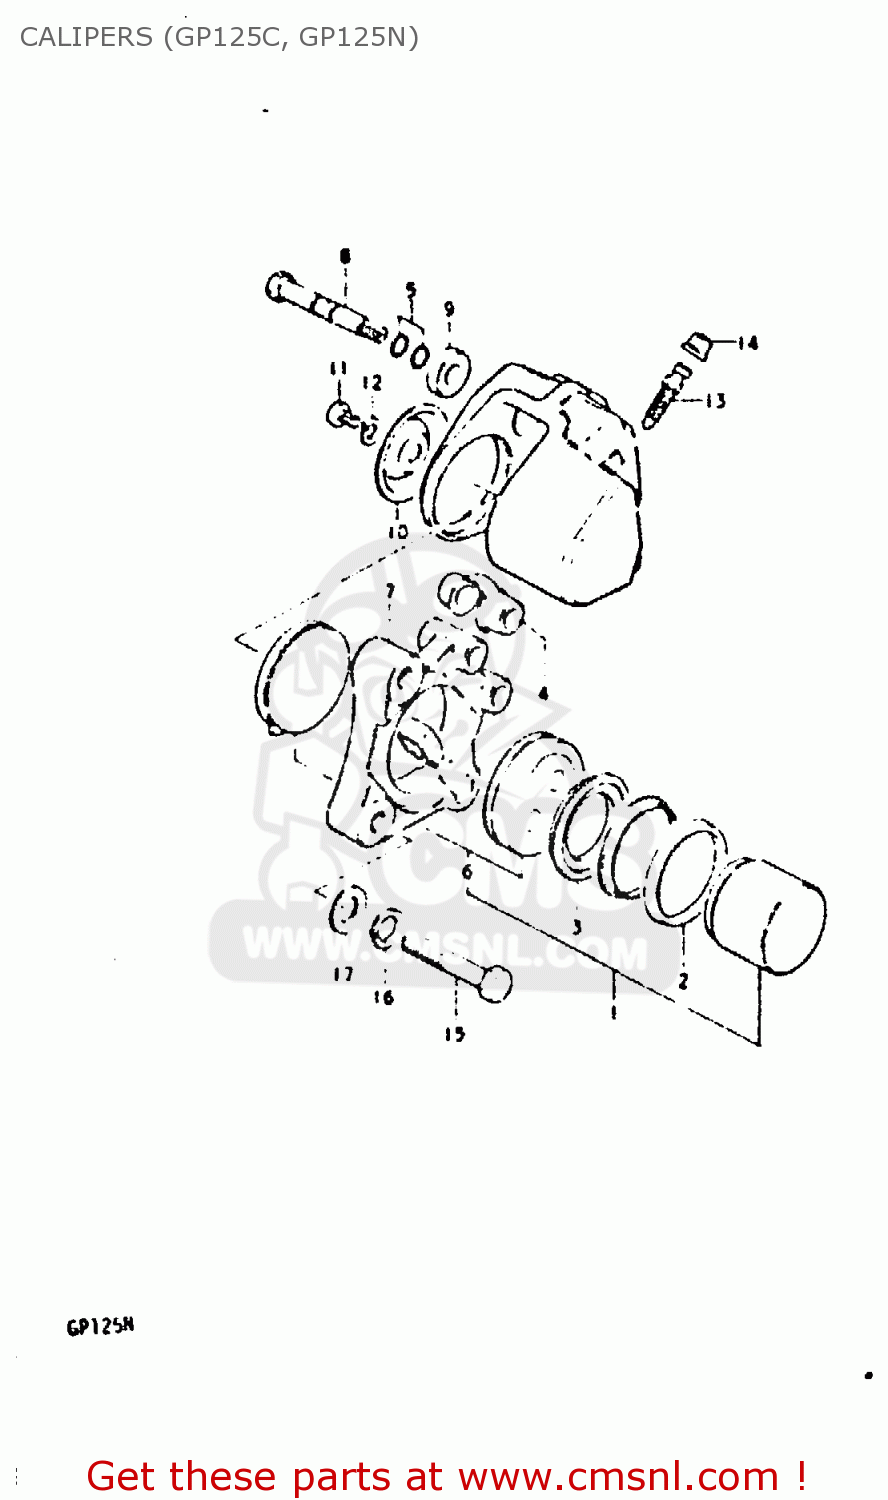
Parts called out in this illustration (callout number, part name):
1	PISTON & PAD SET
2	SEAL,PISTON
3	ROOT, PISTON
4	COVER,AXLE DUST
5	O RING, AXLE
6	PAD SET (MCA)
7	HOLDER, CALIPERS
8	AXLE,CALIPER
9	WASHER, AXLE
10	COVER,HOUSING
11	SCREW
12	LOCK WASHER
13	BLEEDER
14	CAP,BREATHER
15	BOLT
16	WASHER,LOCK,8.
17	WASHER
